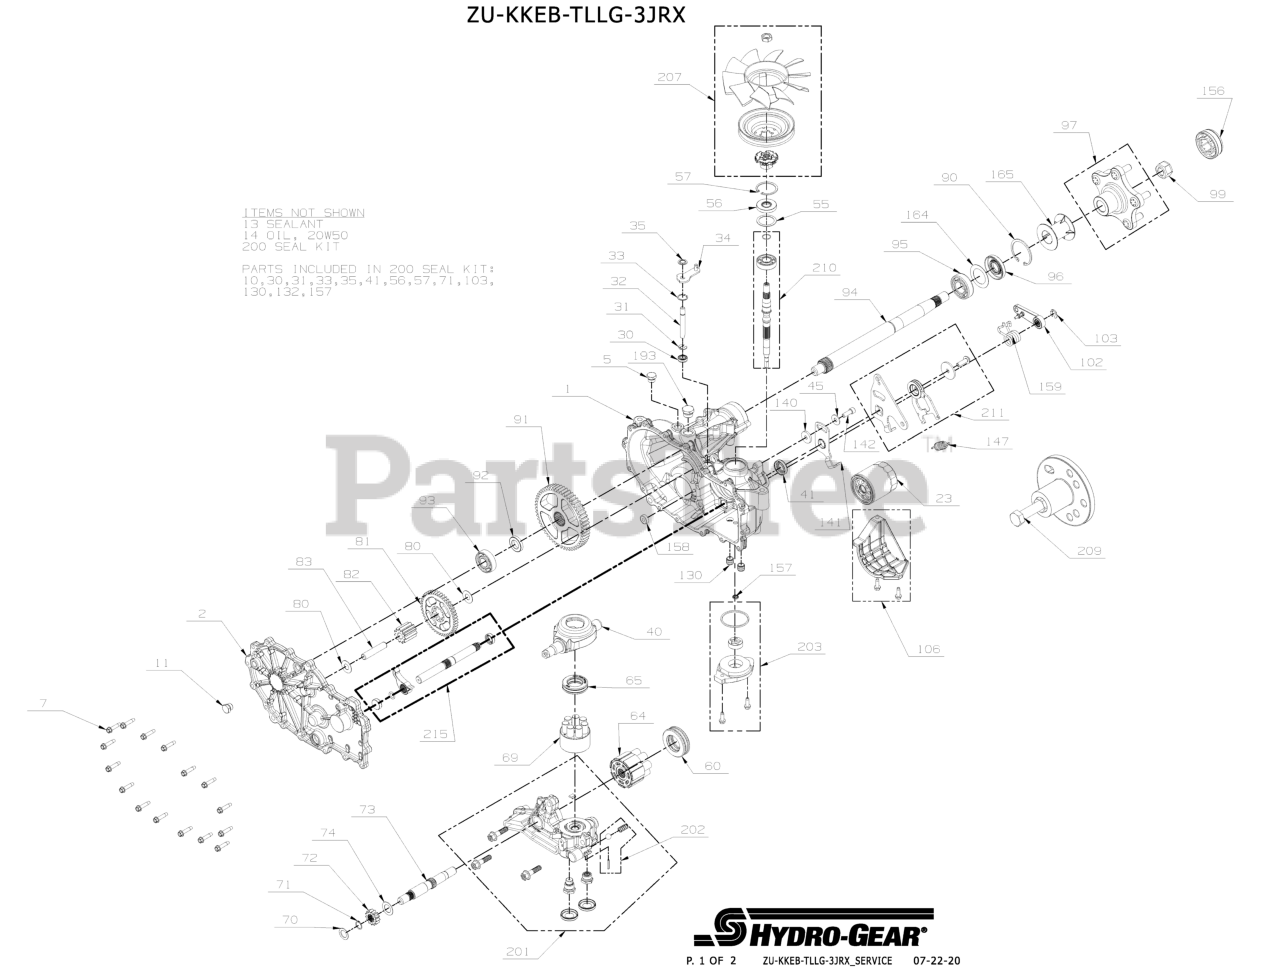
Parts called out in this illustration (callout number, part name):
1	KIT, MAIN HOUSING LH, CHARGE, CONTROL
2	KIT, COVER, SIDE LH
5	PLUG EXT HEX VENT 9/16 18
7	SCREW,HEX WASHER 1/4-20X1.125
11	PLUG EXT HEX VENT 9/16 18
13	SEALANT TUBE 10.1OZ.
14	FLUID, HYDRO 15W50 QT
14	FLUID, HYDRO 20W50 QT
23	FILTER, HYDRO-GEAR 2800 TRANS
30	Seal, lip .375 x 375 x 325
31	RING. RETAINING
32	ROD, BYPASS
33	RING, RET .750
34	HG BYPASS ARM (52370)
35	RING, RTNG .
40	TRUNNION, SWASHPLATE
41	SEAL, LIP 18X32X7
55	WASHER 1.23X1.56X.04
56	SEAL, LIP 17X40X7
57	RING, RET 1.56 INT
60	HG THRUST BEARING (51462)
64	HG 16CC CYLINDER BLOCK (71579)
65	HG THRUST BLOCK (53502)
69	HG SEVEN PISTON BLOCK (71971)
70	WASHER .63X1.0X.05
71	RING, RET 62 EXT
72	GEAR, 13T, STEEL
73	SHAFT, MOTOR
74	WASHER .71 X 1.16 X .04
80	WASHER .5X1.0X.032
82	GEAR 11 TOOTH STEEL
83	JACK SHAFT (PIN)
90	RING, RETAINING
91	GEAR, 54T
92	SPACER
93	KIT, BEARING
94	SHAFT, AXLE
95	BEARING, BALL 25.4 X 52 X 15
96	SEAL, LIP
97	HUB, HYDROGEAR P/N 71691
99	NUT, HEX, LOCK 3/4-16
102	KIT, BRAKE ARM LEFT HAND
103	CLIP,BRAKE ARM HYDROGEAR 52027
106	KIT, FILTER GUARD
130	TUBE CHARGE TRIPLE ORING
141	ARM, NEUTRAL LEFT
142	SHCS 5/16-24X1 PATCH
147	RTN SPRING HG 51605
156	CAP, AXLE
157	KIT GEROTOR SEAL
158	MAGNET, RING
159	SPRING, TORSION, CW
164	WASHER, 1.355 x 2.035 x .021 FLAT
165	TUBE, AXLE 2.03
200	HG SEAL KIT (71976)
201	KIT, CENTER SECTION, LH CHARGE
202	KIT CHARGE RELIEF
203	KIT, CHARGE PUMP
207	KIT, FAN/PULLEY
209	HUB PULLER 5 BLT
210	INPUT SHAFT HG 71978
211	TRN KIT HRDROGEAR P/N 71599
215	KIT, OUTBOARD, RH ROT B / LH ROT A
